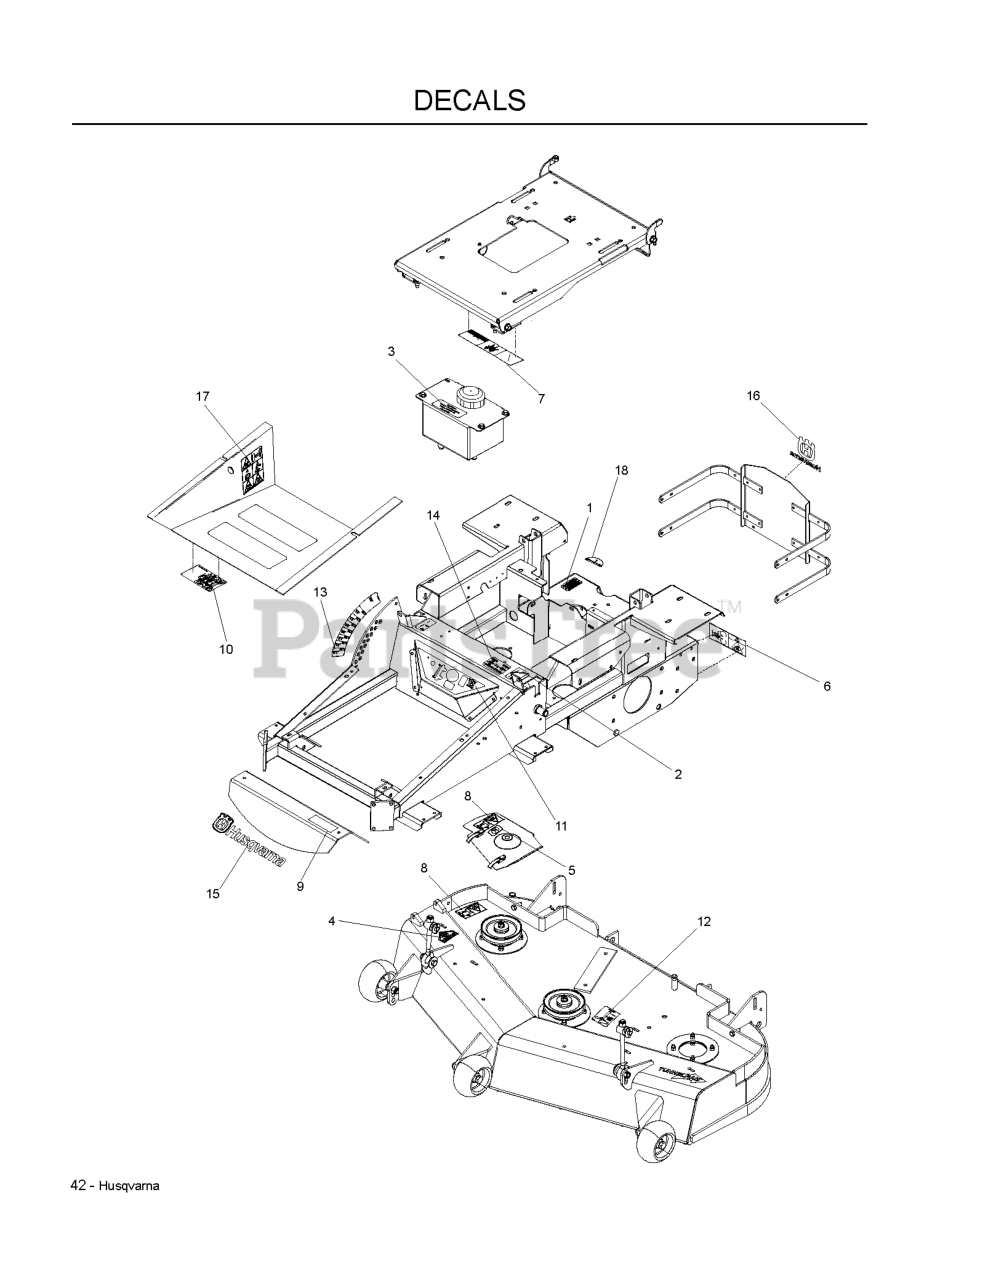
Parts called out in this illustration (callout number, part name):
1	DECAL, PROP. 65
2	DECAL, MOTION CONTROL
3	DECAL, OIL TANK
4	DECAL, CPSC
5	DECAL, NO STEP
6	DECAL, BELT DRIVE
7	EURO DECAL-BATTERY WARNIN6
8	DECAL, EURO SEVERING
9	DECAL, IZ5223
10	SERVICE DECAL
11	DECAL, CONSOLE
12	DECAL, BELT ROUTING
13	DECAL, HEIGHT ADJ
14	DECAL, F.S.T.
15	DECAL, HUSQ 12" BLUE
16	DECAL, CROWN H 5-1/4 SILVER
17	DECAL, WARNING
18	DECAL, FUEL VALVE
